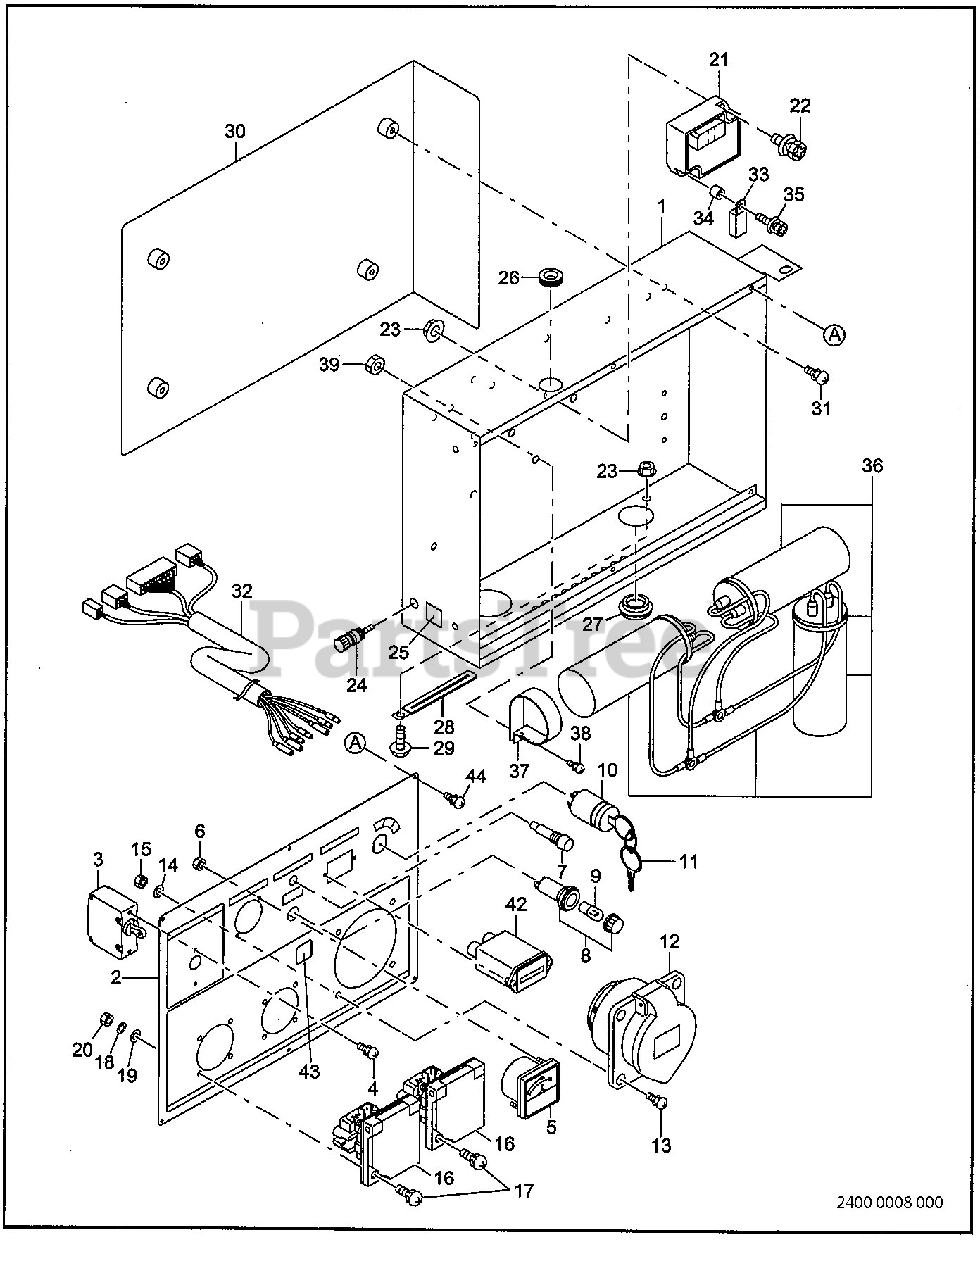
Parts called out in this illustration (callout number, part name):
1	CONTROL BOXASSY
1	CONTROL BOX ASSY
1	CONTROL BOX UNIT
2	CONTROL PANEL ASS
2	CONTROL PANEL
3	NO FUSE BREAKER (1P-35A)
4	SCREW and WASHER ASSY
8	LAMP (OIL)
9	LAMP (18V-0.11A)
10	KEY SWITCH
12	AC RECEPTACLE (240V-32A)
13	SCREW and WASHER ASSY
16	AC RECEPTACLE (250V-16A)
17	SCREW
21	ECU(O/S & R/C) ASSY
22	SCREW and WASHER ASSY
23	FLANGE NUT
29	FLANGE BOLT
31	SCREW and WASHER ASSY
32	WIRE ASSY
35	SCREW
36	CONDENSER ASSY (3711Fx3)
37	CONDENSER BRACKET
38	SCREW and WASHER ASSY
43	LABEL (electric shock)
44	SCREW and WASHER ASSY
